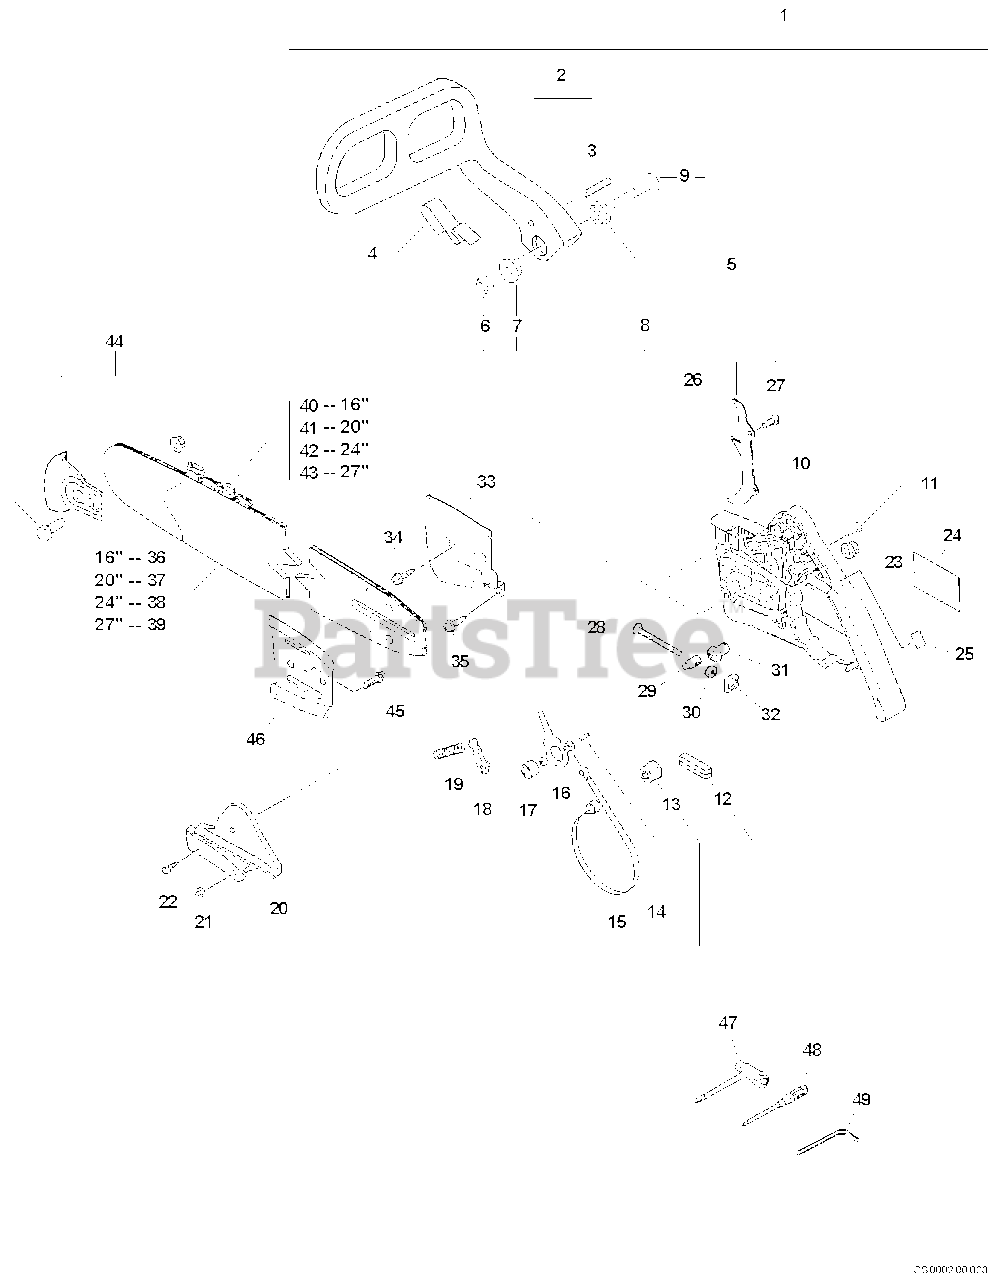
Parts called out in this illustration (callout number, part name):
1	CHAIN BRAKE ASSY
2	LEVER, BRAKE
3	PIN - 3.5X26
4	SPRING, RETURN
5	MOUNTING KIT
8	COLLAR - 5
9	SCREW - 5X35
10	GUARD, SPROCKET
11	SCREW - 3X18
13	ADJUSTER, BRAKE BAND
14	PIN - SPRING -- 4X8
15	BAND, BRAKE
16	LEVER, BRAKE
17	SPACER - 8
18	STOPPER, BRAKE
19	SPRING, BRAKE
20	COVER, BRAKE
22	SCREW - 4X12
23	NUT - FLANGE
24	LABEL - ECHO
25	LABEL - CAUTION
26	SPIKE KIT
27	SCREW - 5X12
28	SCREW, TENSIONER
29	TENSIONER, CHAIN
30	GEAR - BEVEL
31	GEAR - PINION
32	COLLAR - 8
33	PLATE, GUIDE - OUTER
34	SCREW - 3X6
35	SCREW - 4X10
36	GUIDE BAR - 16" (40cm)
37	GUIDE BAR - 20" (50cm)
38	GUIDE BAR - 24" (60cm)
39	GUIDE BAR - 27" (68cm)
40	SAW CHAIN - 16" (40cm)
41	SAW CHAIN - 20" (50cm)
42	SAW CHAIN - 24" (60cm)
43	SAW CHAIN - 27" (68cm)
44	KICK GUARD KIT
45	SCREW - 4X8
46	PLATE, GUIDE - INNER
47	T-WRENCH - 13X19mm
48	SCREWDRIVER
49	HEX KEY - 4mm
